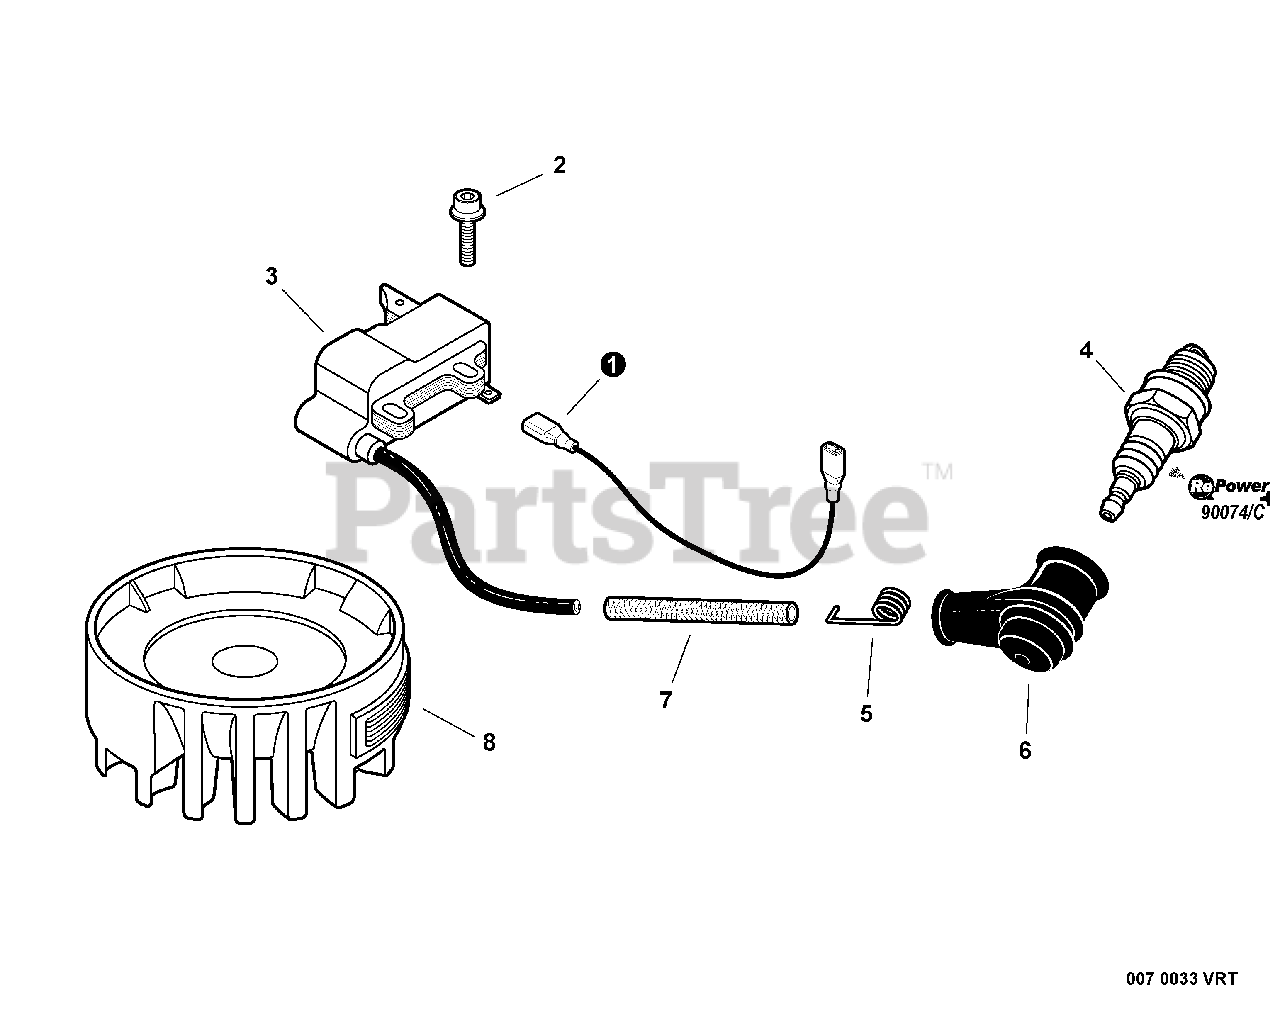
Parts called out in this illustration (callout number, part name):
1	LEAD - IGNITION
2	BOLT 4×20
3	COIL, IGNITION
4	SPARK PLUG - BPM8Y
4	SPARK PLUG - BPMR8Y
5	TERMINAL, SPARK PLUG
6	CAP, SPARK PLUG
7	TUBE, INSULATOR 7×8.6×55
8	FLYWHEEL
9	TUNE-UP KIT - REPOWER
